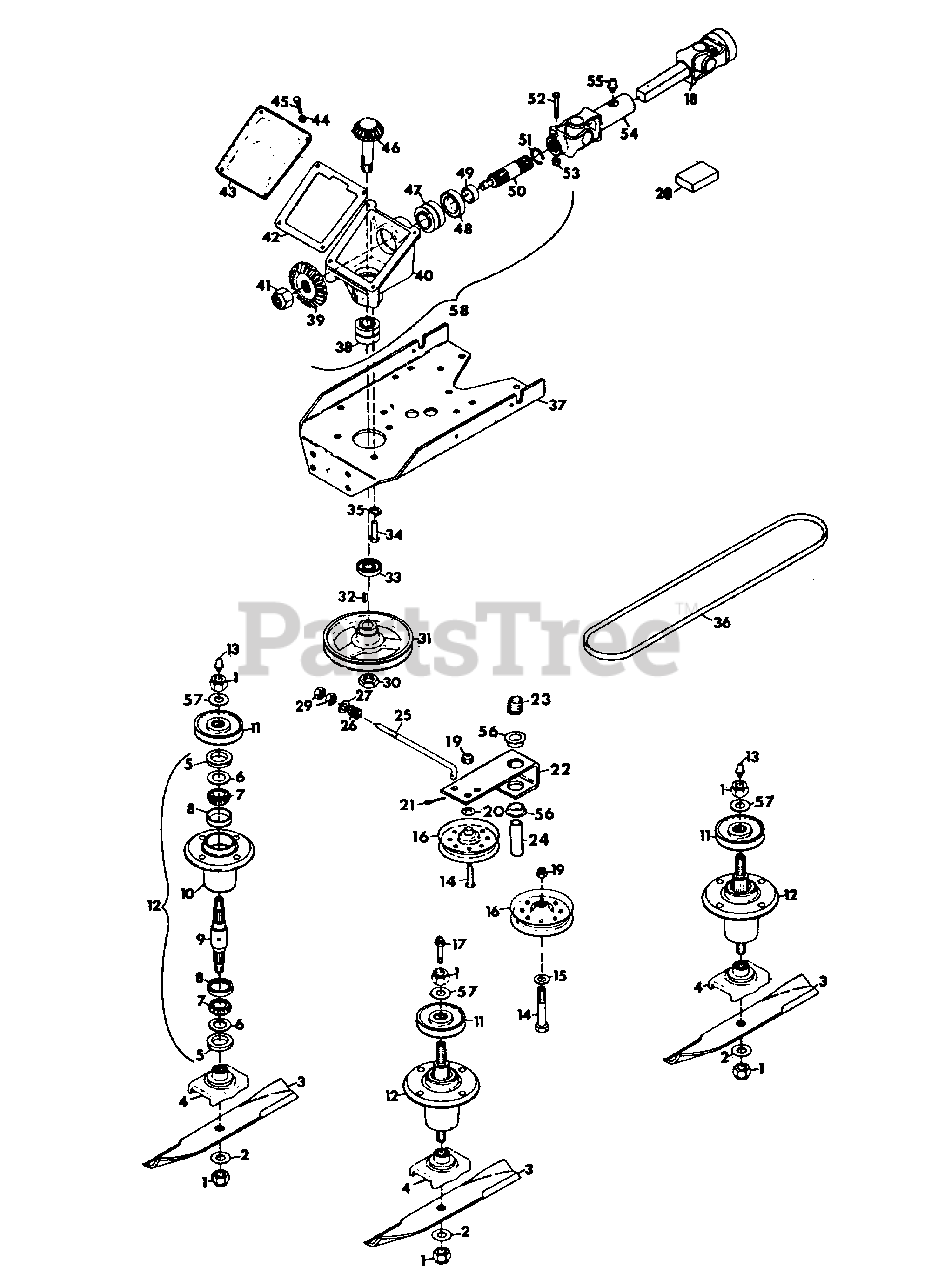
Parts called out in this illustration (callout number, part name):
1	NUT, LOCK 5/8-11
2	WASHER, FLAT .656X1.312X.095
3	BLADE, 50" MOWER
3	BLADE, 40" MOWER
4	CRADLE, BLADE
5	SEAL, STEEL
6	WASHER, FLAT .975X1.970X.030
7	CONE, ROLLER BEARING
8	CUP, ROLLER BEARING
9	SHAFT, SPINDLE
10	HOUSING, BEARING
11	SHEAVE, SPINDLE 40" MOWER
11	SHEAVE, SPINDLE 50" MOWER
12	ASSEMBLY, SPINDLE
13	FITTING, LUBE 1/8
14	BOLT, HEX 3/8-16X2.00
15	WASHER, FLAT .438X1.000X.083
16	SHEAVE, IDLER
17	FITTING, LUBE .125 EXT. 90 DEG.
18	SHAFT, PROP. SQ. BAR
19	NUT, LOCK 3/8-16
20	SPACER, IDLER .406X.750X.188
21	PIN, COTTER 3/32X1.00
22	ARM, IDLER PIVOT
23	SPRING, COMP.
24	SPACER
25	ROD, IDLER 50" MOWER
25	ROD, IDLER 40" MOWER
26	SPRING, COMP. 1X.78X338 LB/IN
27	WASHER, FLAT .406X.812X.065
28	KIT, REPAIR UNIV. JT. ROCK. STD.
28	KIT, REPAIR UNIV. JT.(NEAPCO)
29	NUT, HEX 3/8-24
30	NUT, JAM 3/4-10 HEX HEAVY
31	SHEAVE, 1/2X6.50
32	KEY, WOODRUFF .188X.625 HARD
33	SEAL, OIL 1.250X1.686X.313
34	BOLT, HEX 1/2-13X1
35	WASHER, LOCK 1/2
36	BELT, 40" MOWER
36	BELT, V .500X.312X126.3
37	SUPPORT, GEAR HOUSING
38	ASSEMBLY, BEARING .750X1.781X1.499
39	GEAR, BEVEL
40	CASTING, GEAR BOX
41	NUT, LOCK 3/4-10
42	GASKET, GEAR HOUSING
43	COVER, GEAR HOUSING
44	WASHER, LOCK 1/4
45	BOLT, HEX 1/4-20X.50
46	SHAFT, GEAR PINION
47	ASSY., BEARING 1.000X1.980X1.243
48	SEAL, OIL 1.250X1.987X.250
49	SPACER
50	SHAFT, DRIVE
51	RING, RETAINING 1.000 SHAFT
52	BOLT, HEX 1/4-20X2
53	NUT, LOCK 1/4-20
54	U-JOINT, FEMALE END
55	FITTING, LUBE 1/4-28
56	BUSHING, NYLON .760X1.000X.600
57	WASHER, FLAT .687X1.312X.122/.146
58	ASSEMBLY, DRIVE
